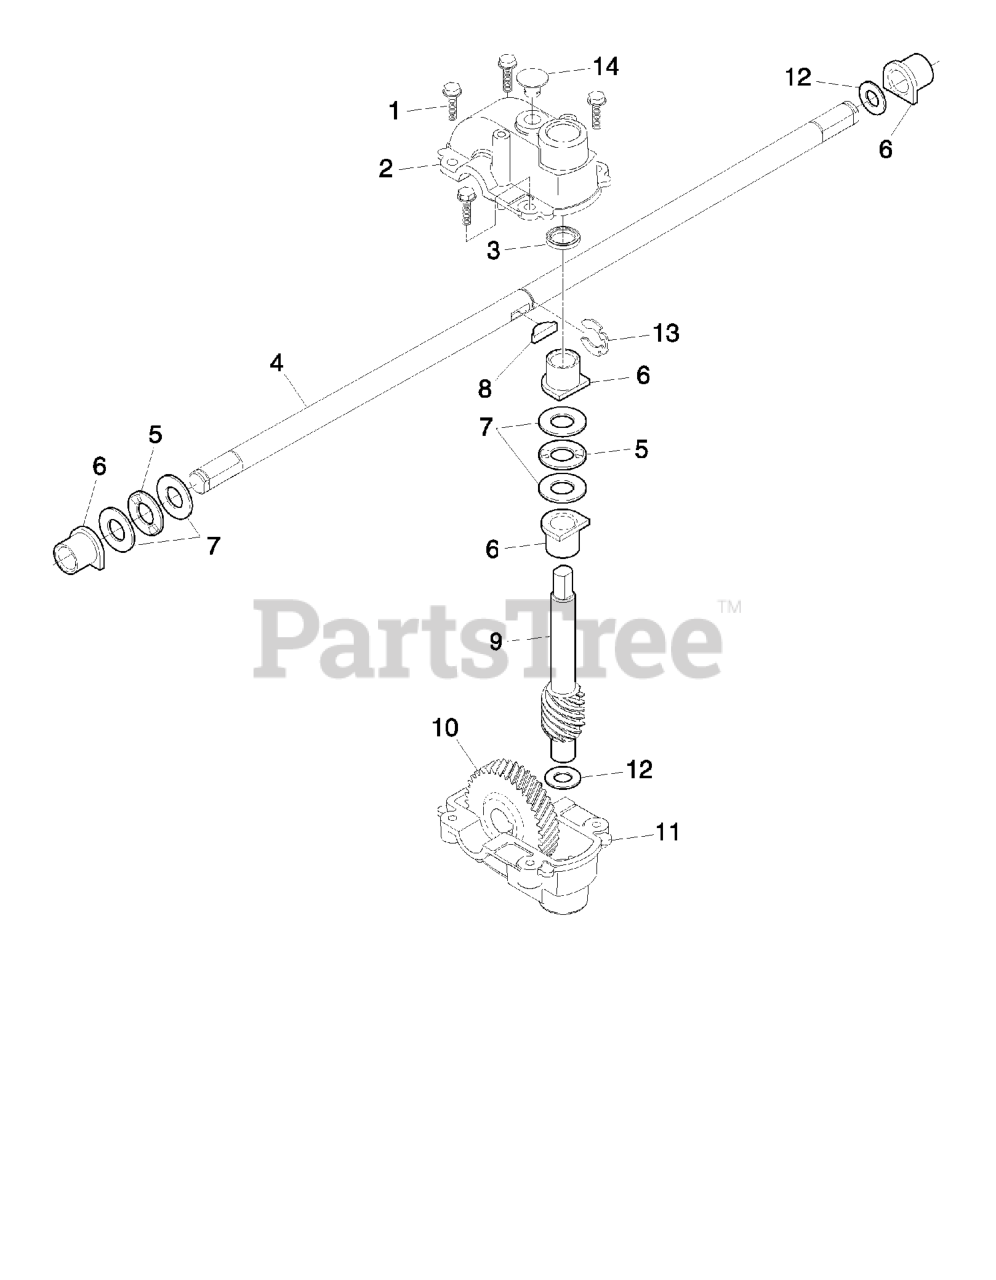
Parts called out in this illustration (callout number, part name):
1	Screw, Hex Washer Head #10-24 x .668
2	GEAR CASE, UPPER
4	SHAFT.DRIVE.HI-VAC.EZ
5	BEARING, NEEDLE, THRUST
6	BEARING
7	WASHER, THRUST
8	HI PRO KEY
9	SHAFT.WORM.HI-VAC
10	GEAR, HELICAL
11	GEAR CASE, LOWER
12	THRUST WASHER
13	KLIP RING
14	PLUG.AUGER.GEAR.BOX.SNOW
